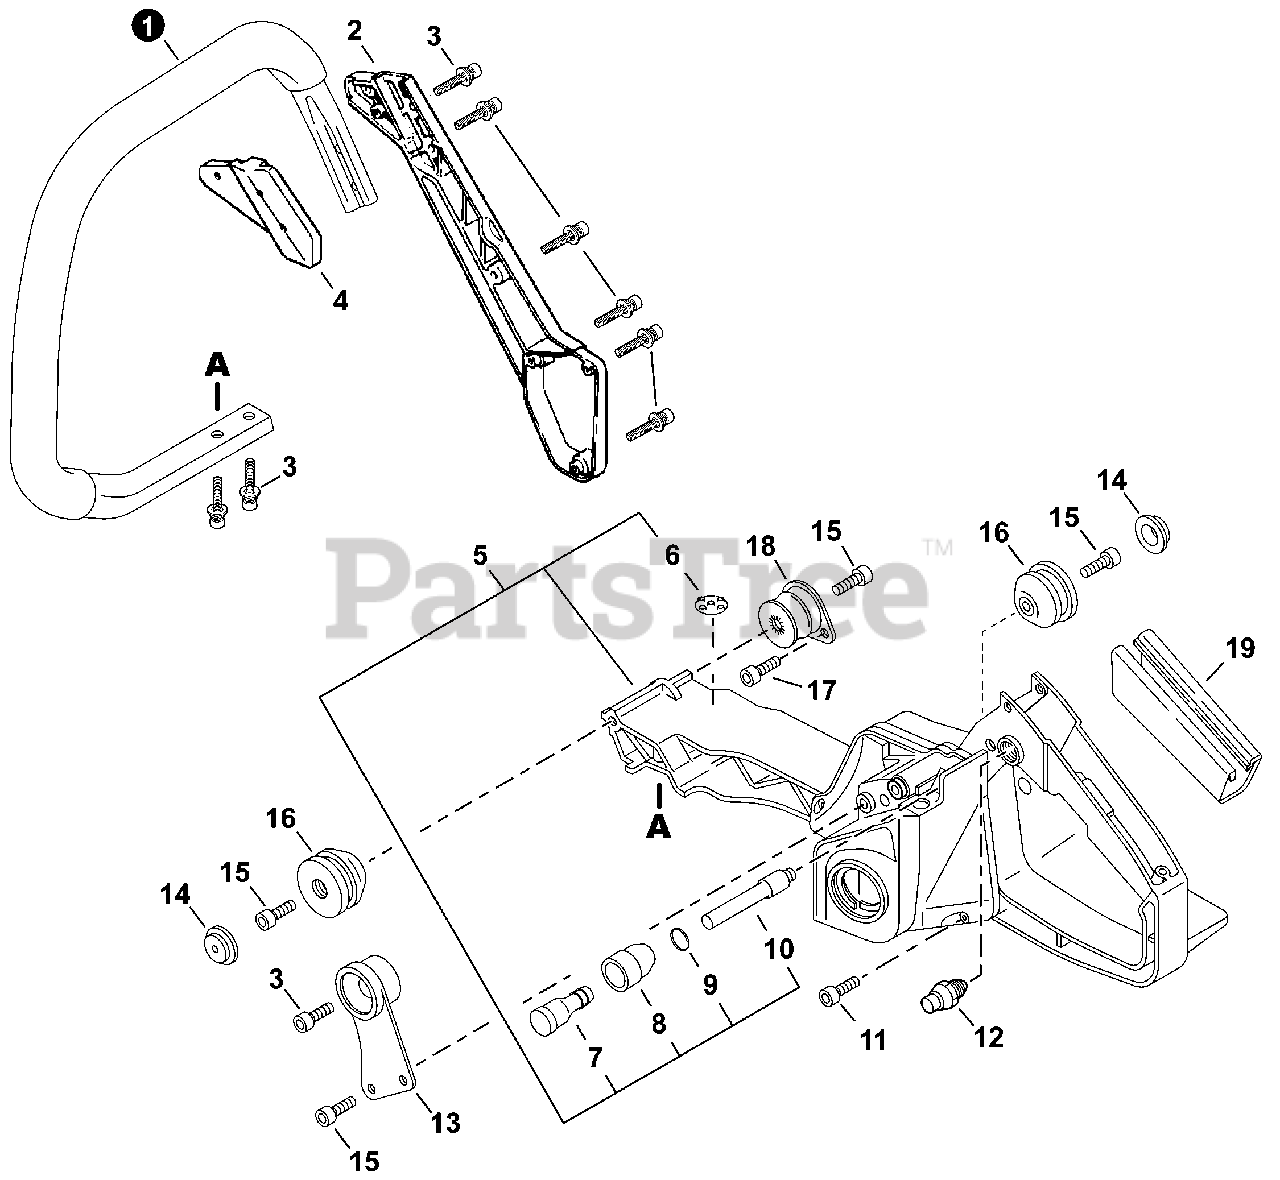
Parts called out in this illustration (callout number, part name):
1	HANDLE, FRONT
2	SUPPORT, HANDLE - GRAY
2	SUPPORT, HANDLE - BLACK
3	BOLT 5x20
4	BRACKET, HANDLE - GRAY
4	BRACKET, HANDLE - BLACK
5	HANDLE ASSY, REAR - GRAY
5	HANDLE ASSY, REAR - ORANGE
7	VENT ASSY
8	HOLDER, VENT
9	CLIP 5.5
10	PIPE 3x5x90
11	SCREW 4x14
12	LOCK, THROTTLE TRIGGER
14	CAP, CUSHION
15	BOLT 5x14
17	BOLT 4x10
19	GRIP, HANDLE
